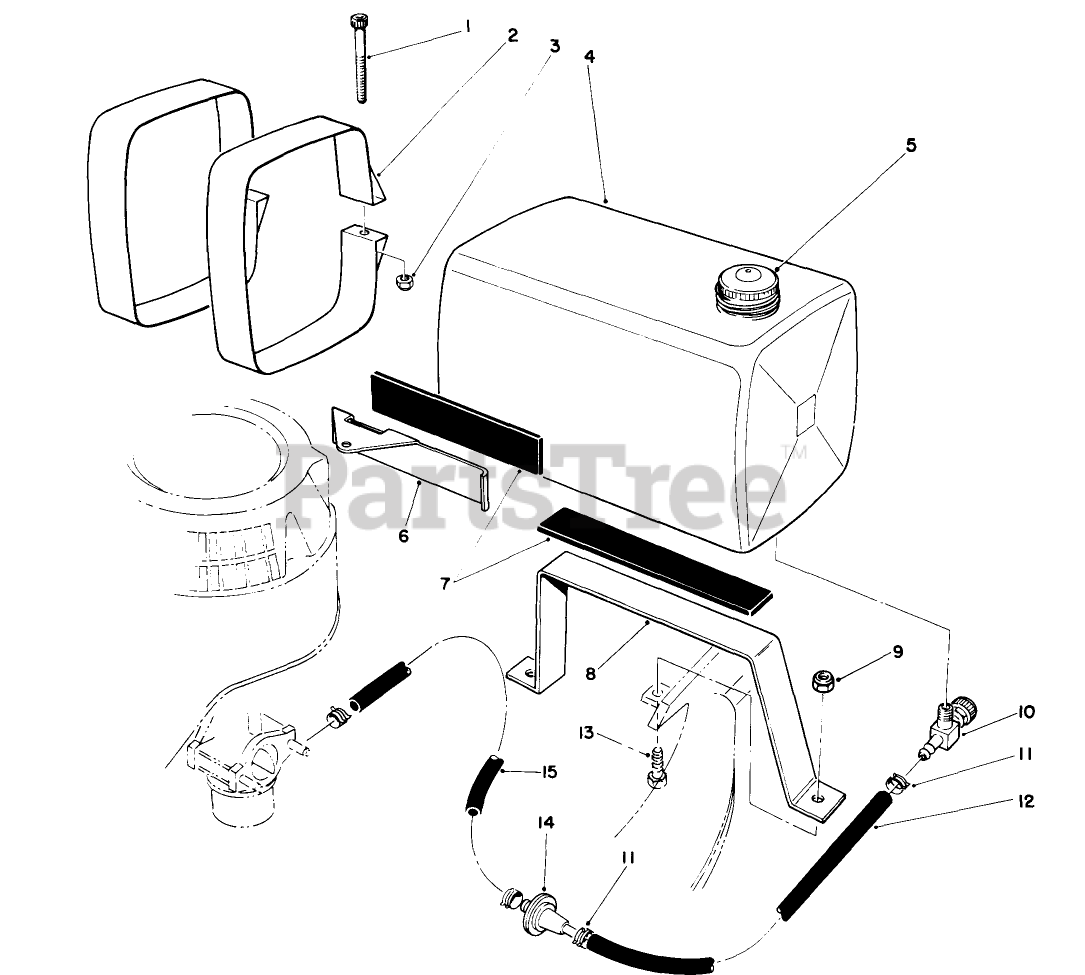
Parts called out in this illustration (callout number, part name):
1	SCREW-HSH
2	TANK STRAP WA
3	NUT-HEX
4	5 QT GAS TANK
6	FRT TANK MOUNT *
7	ISOLATOR PAD
8	TANK BOTTOM MOUNT *
9	NUT-LOCK, NI
11	CLAMP-FUEL LINE
12	HOSE-FUEL
13	SCREW-HH
14	FILTER-FUEL
15	HOSE-FUEL
